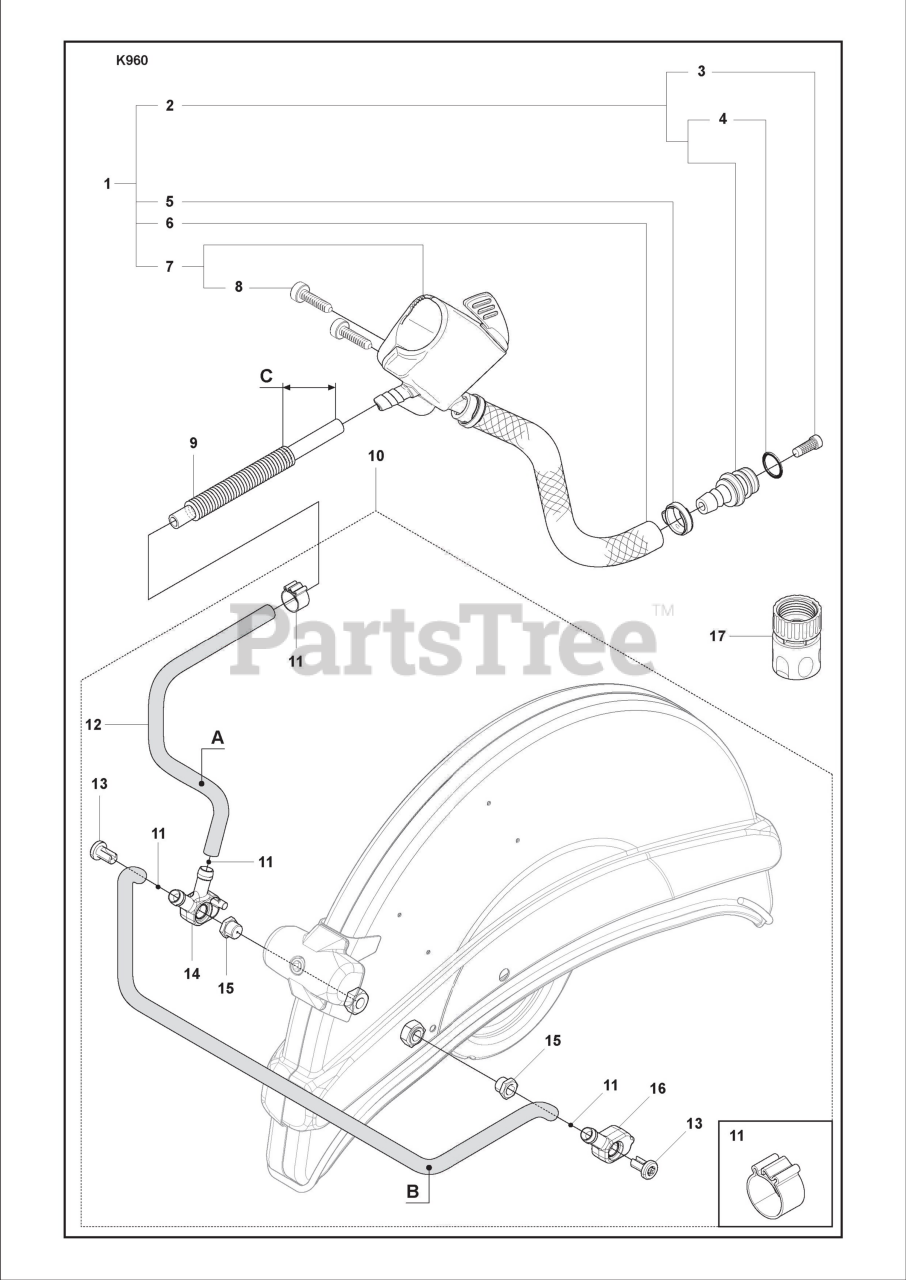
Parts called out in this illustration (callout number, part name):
1	Hose Kit
2	Nipple
5	Hose Clamp
7	Valve Assy
9	Protective Spring
11	Hose Clamp
12	Hose
17	Coupler
